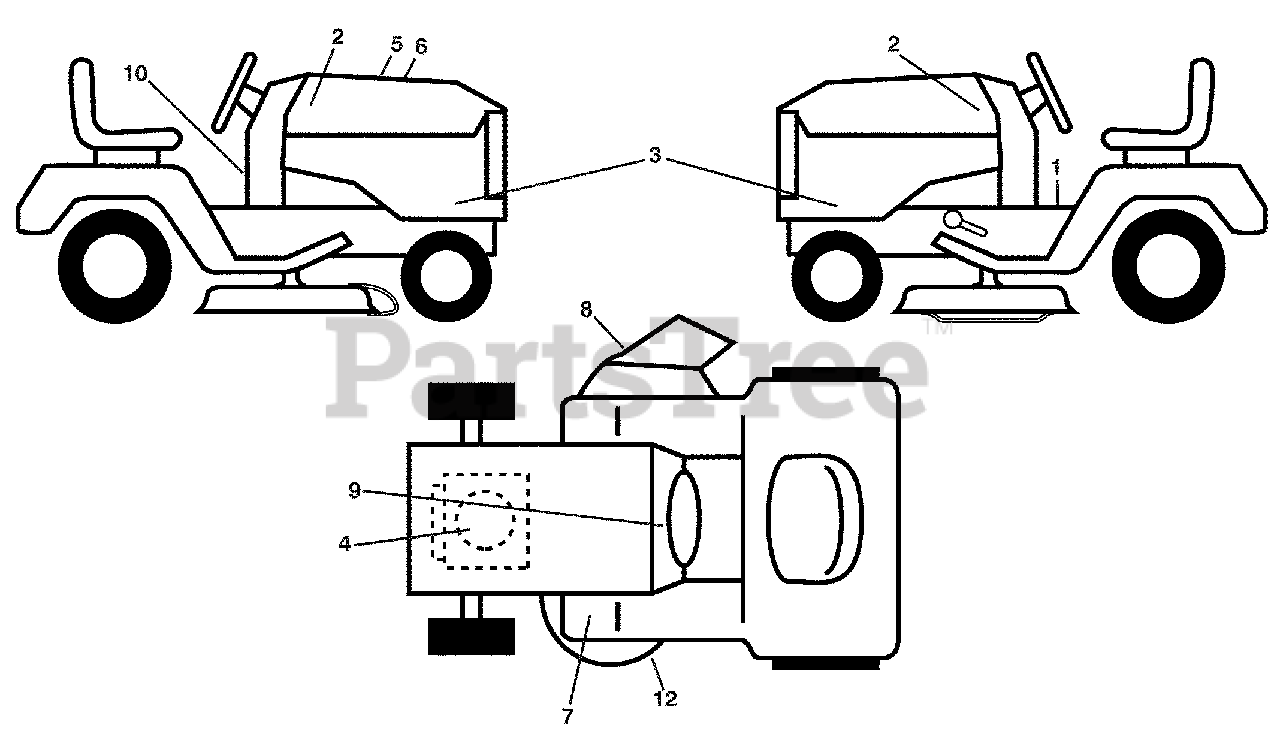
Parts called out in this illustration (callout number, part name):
1	Decal, Operators
2	Decal, Hood
3	Decal, Emblem Panel SD
4	Decal, Engine
5	Decal, Customer Respons.
6	Decal, Replacement
7	Decal, Pedal Husq. Crown
8	Decal Mower Warn Keep Hand away
9	Decal, Battery Dnge/Poi
10	Decal, Warning Spark Arrestor
12	Decal, Mower V-Belt Schematic
